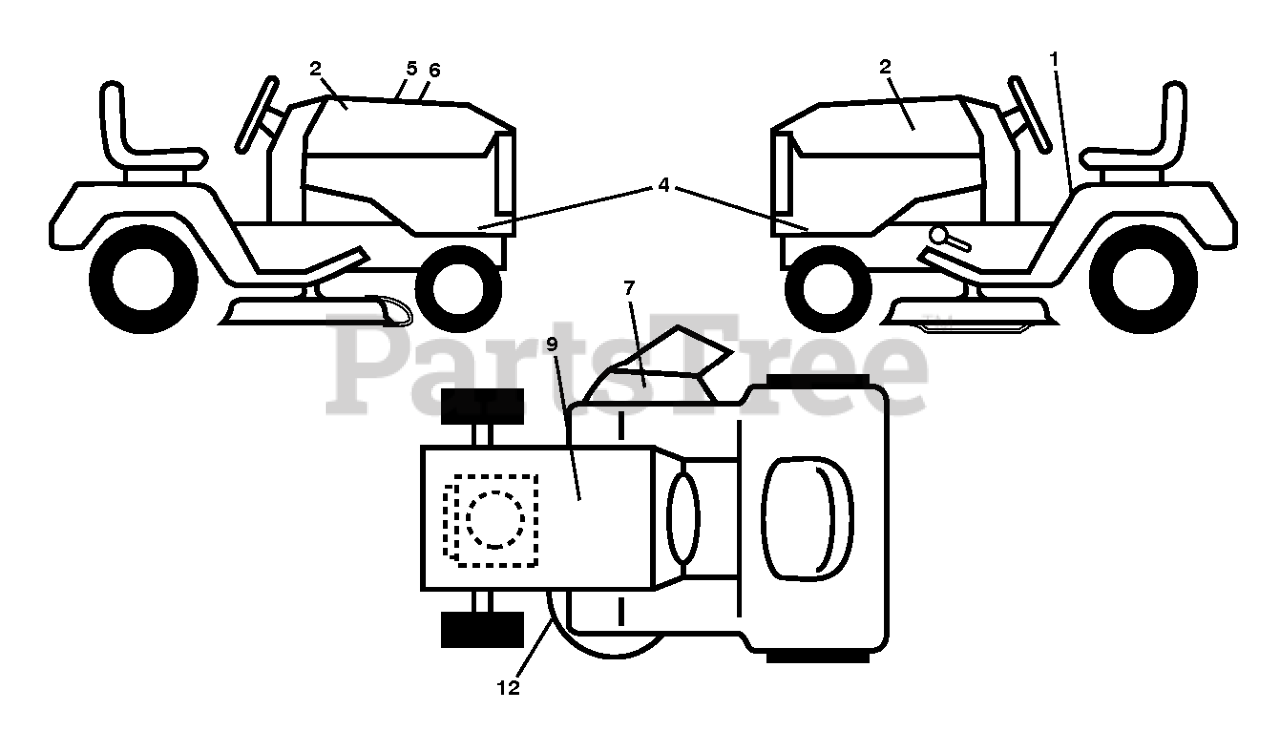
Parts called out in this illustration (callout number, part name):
1	DECAL.FENDER.WARNING.ENGLISH
2	DECAL.BADGE.170MM.TEXTLOGO.
4	DECAL HOOD PANEL
5	DECAL.WARNING.CUST.RESP.E85.
6	DECAL.RPL.KW.FR.TLW.42E.
7	DECAL, DECK DEFLECTOR, WARNING
9	DECAL BTRY SYMBOLS
12	DECAL.V-BELT.SCH.42/46"MEC/ELE
